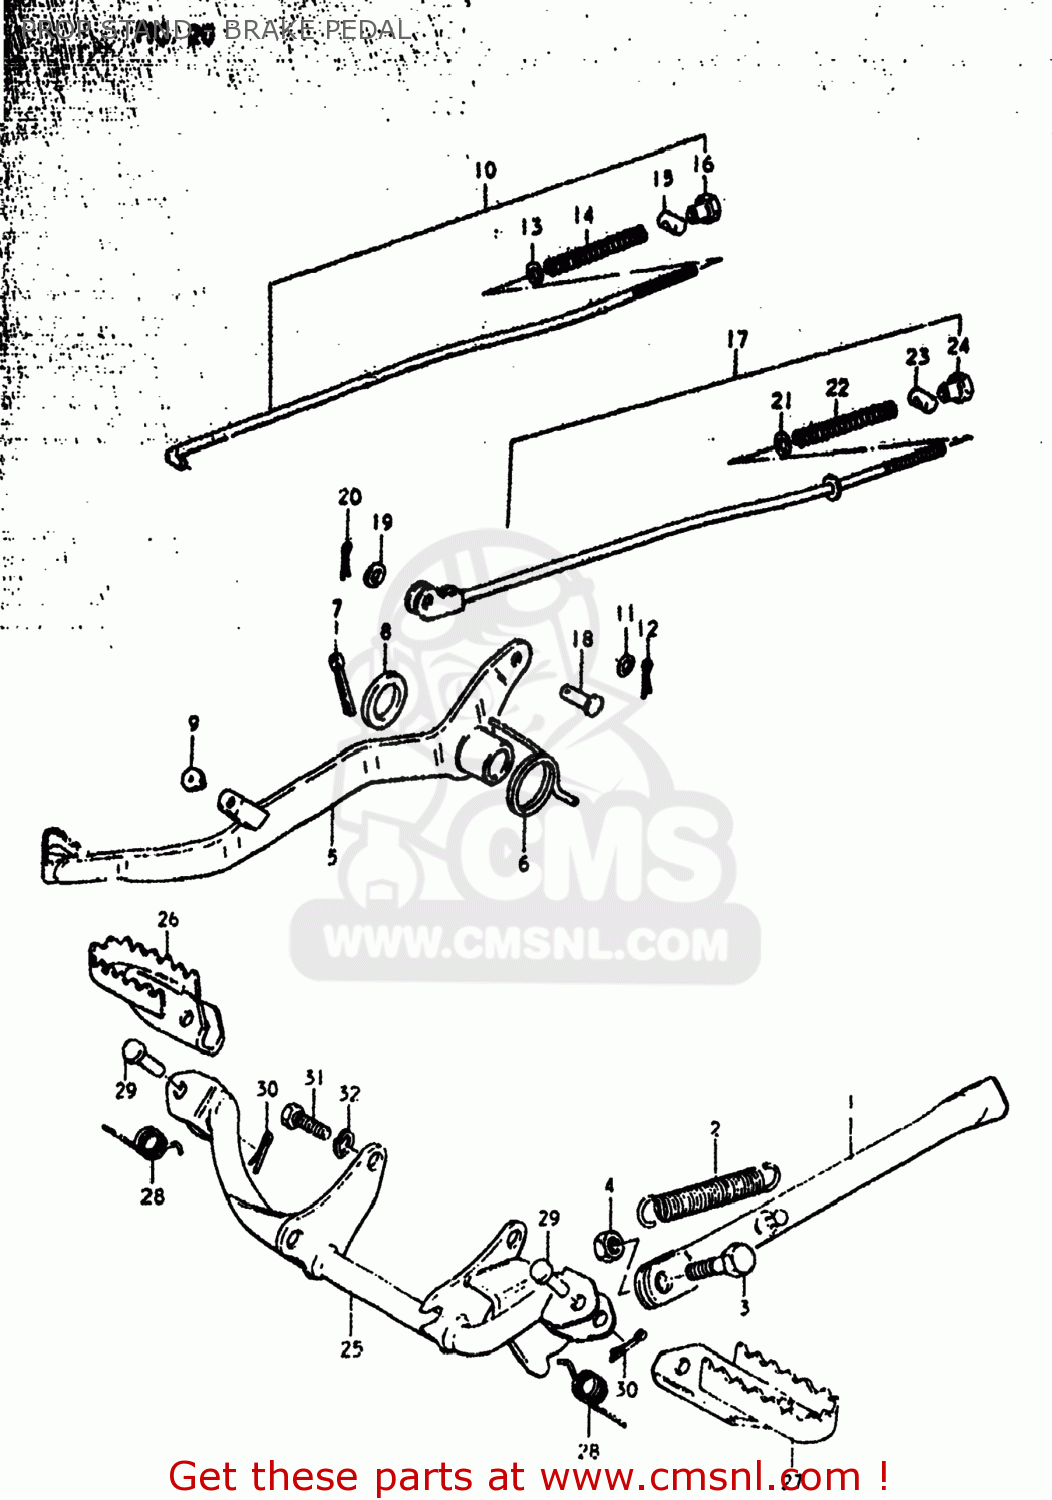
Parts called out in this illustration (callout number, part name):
1	STAND,SIDE
2	SPRING
3	BOLT
4	NUT
5	PEDAL,BRAKE
6	SPRING
7	COTTER PIN
8	WASHER(15.5X26X2.3)
9	STOPPER,BRAKE PEDAL
10	ROD ASSEMBLY,REAR BRAKE
11	WASHER
12	PIN 20X20
13	WASHER
14	SPRING
15	PIN(11X18)
16	NUT
17	ROD ASSEMBLY,REAR BRAKE
18	PIN(L:13.5)
19	WASHER
20	PIN 20X20
21	WASHER
22	SPRING
23	PIN(11X18)
24	NUT
25	BAR,FRONT FOOTREST
26	FOOTREST,FRONT,RIGHT
27	FOOTREST
28	SPRING
29	PIN
30	PIN 20X20
31	BOLT
32	LOCK WASHER
